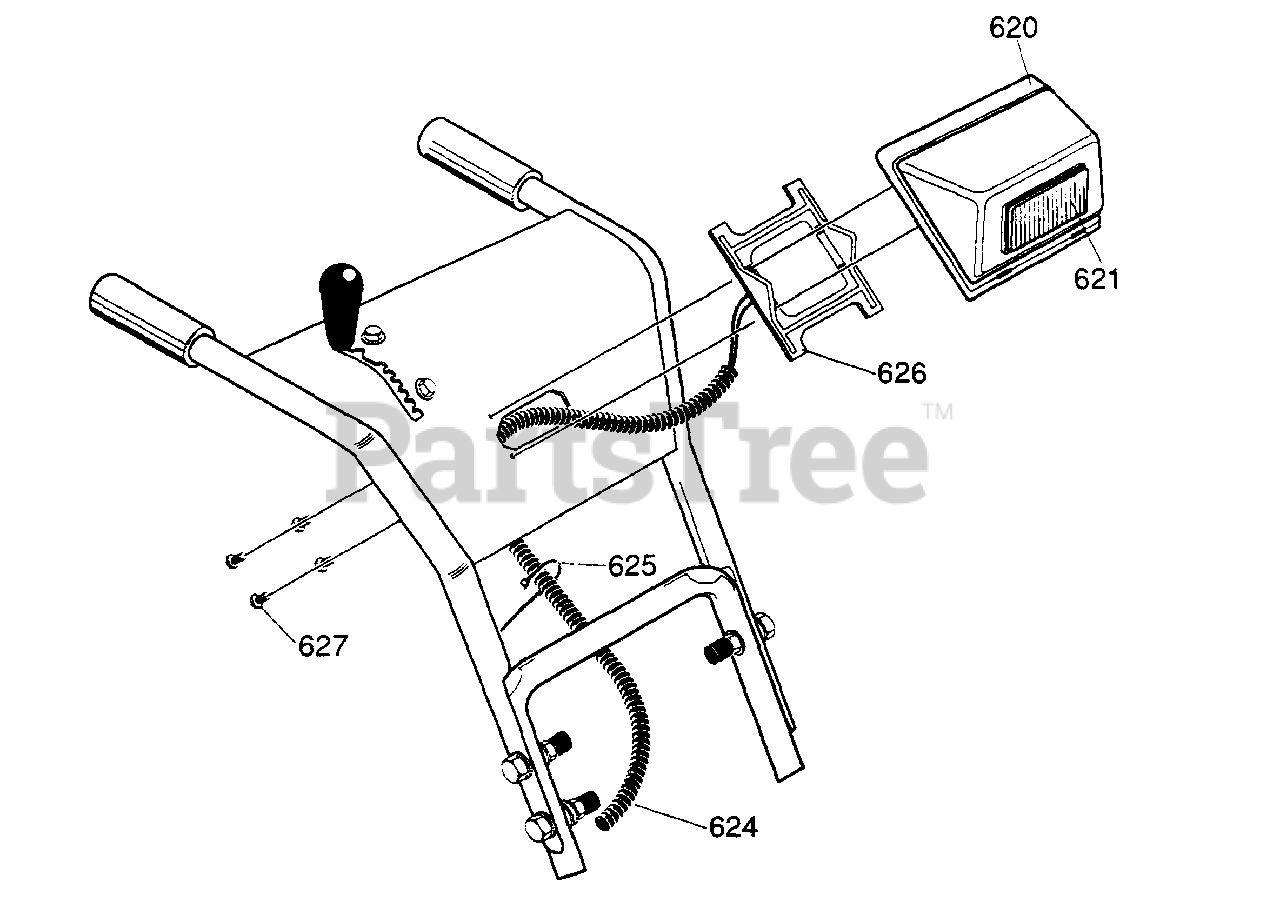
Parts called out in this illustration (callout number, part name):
620	HOUSING, LIGHT B/S
621	HEADLIGHT ASSY.
624	ASSY, HEADLIGHT WIRE HARNESS
626	BRACKET, LIGHT PANEL
627	SCREW, #8X.75 PANTAPP
